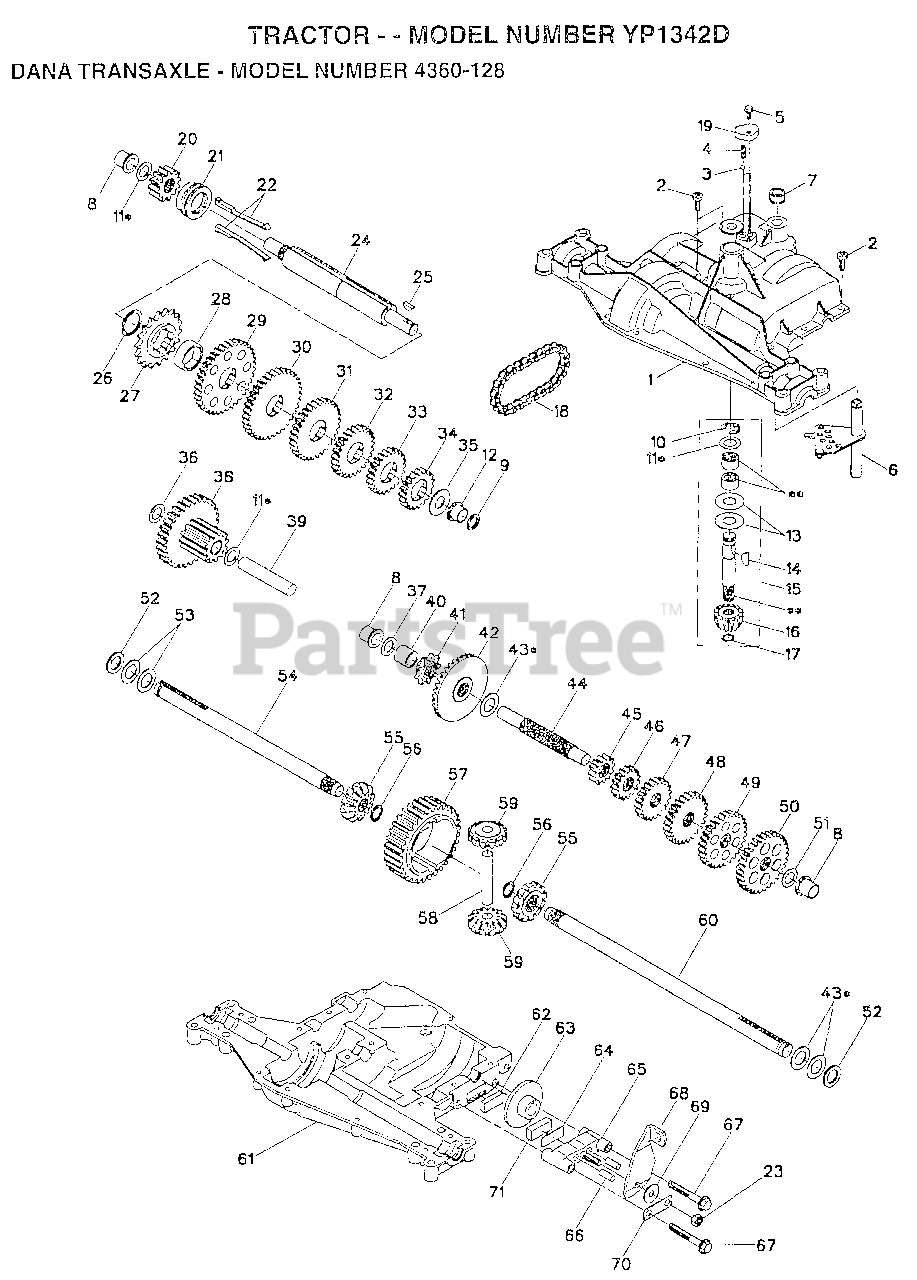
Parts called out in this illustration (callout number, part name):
1	HOUSING.UPPER(5305-P)
4	"SPRING, DETENT LT"
5	SCREW.TAPPING.1/4-20X.734
6	KIT SHIFTER ASM
9	SEAL.OIL.DAN.5508
10	RETAINING RING LT
11	ASM KIT SHIM 4689
12	BEARING.FLNG.5511
13	WASHER T
14	KEY WOODRUFF-DANA
15	INPUT SHAFT KIT 6250
16	PINION.BEVEL.12T(5620)
17	"RING,RETAINING LT"
18	"CHAIN,24 PTCH LT"
19	COVER.DETENT.(5584)
20	GEAR.SPUR.12T.(5627)
21	CLUTCH.COL.5467
22	ASM KIT CLTCH KEY
23	NUT.LOCK.5/16-24
24	SHAFT INTERM DANA
25	WOODRUFF KEY
26	"RING,RETAINING LT"
27	SPROCKET 18T T
28	SPACER YT
29	GEAR SPUR 37 TTH
30	GEAR SPUR 35 TTH
31	GEAR SPUR 30T
32	GEAR 25T LT
33	GEAR SPUR 22 TT
34	SPUR GEAR 19T
35	"WASHER, PLAIN LT"
36	WASHER 045
37	WASHER 031
38	ASSY.GEAR.6153 12T&30T
39	SHAFT IDLER
40	SPACER T
41	SPROCKET 9T LT
42	GEAR.BEVEL.36T(5621)
43	ASM KIT SHIM
44	SHAFT T
45	GEAR SPUR 12 TTH
47	GEAR SPUR 20T
48	"GEAR, SPUR 25T LT"
49	GEAR 28T T
50	"GEAR, SPUR 31T LT"
51	WASHER 060
52	NEOPRENE WASHER
53	WASHER 031
54	AXLE.LH(5528-1)
55	MITER 5270 12T.SPLINED
56	RING.RETAINING.(5270)
58	SHAFT T
59	MITER 5623.12T.IDLER
60	AXLE.RH.(5528-2) DANA
61	HOUSING.KIT (6088)
62	PUCK T
63	BRAKE DISC. T
64	SPACER LT
66	PIN T
67	SCREW.(5562) .5/16-18X2.35
69	WASHER LT
70	BRACKET, ANTI-ROTATION
71	PUCK T
